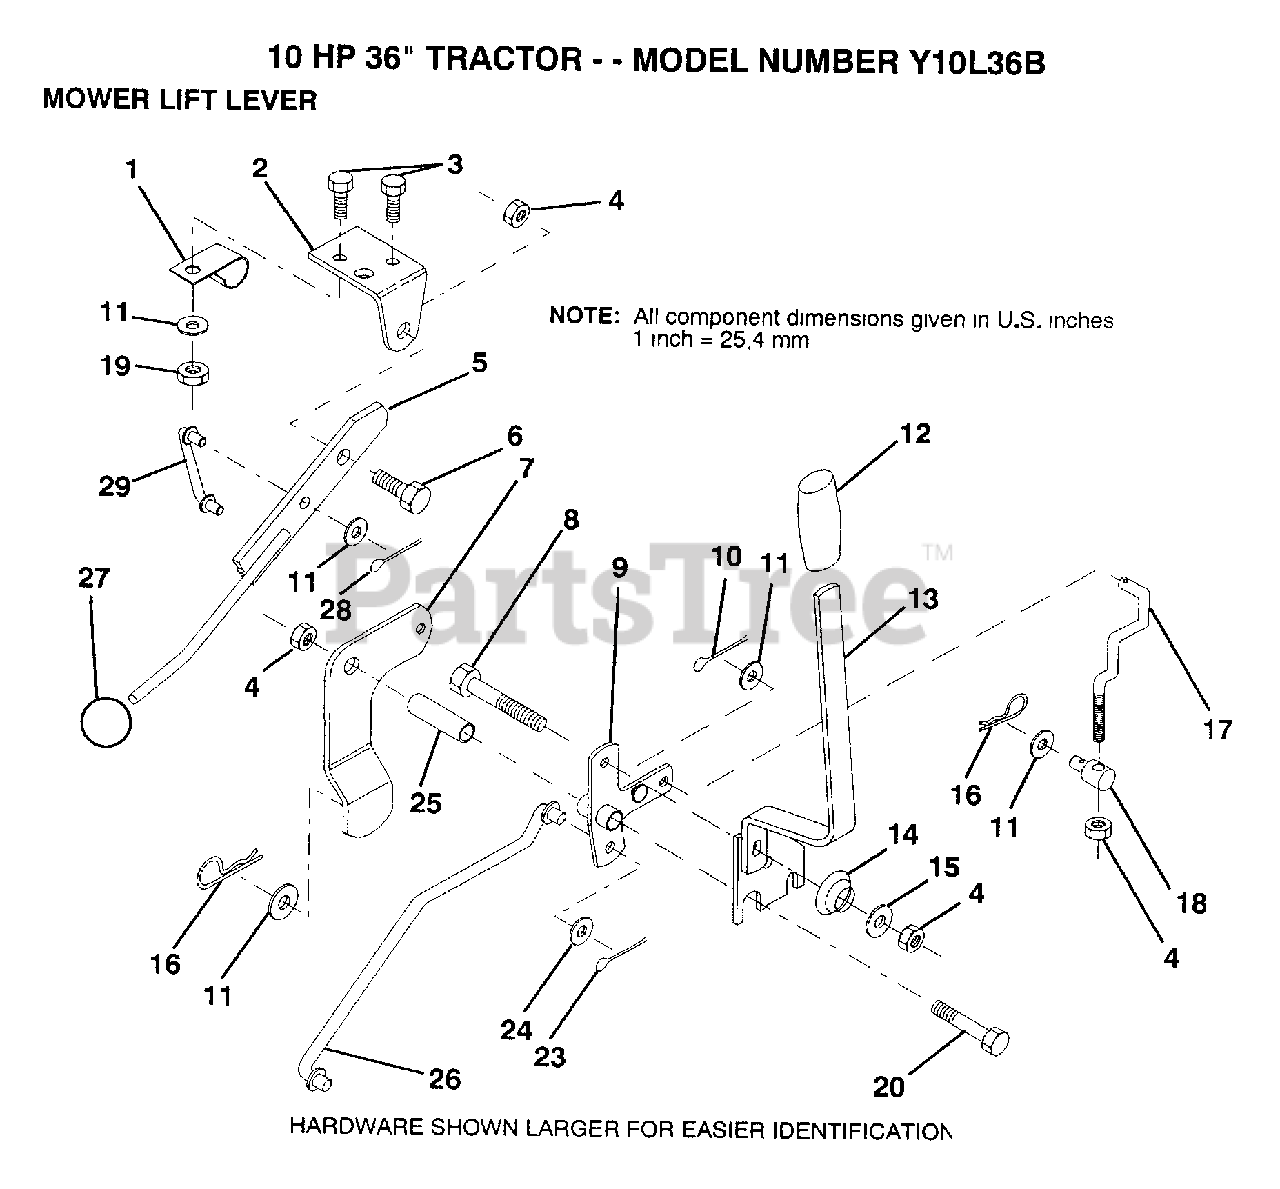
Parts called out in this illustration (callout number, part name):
1	"CLIP,INSULATOR"
2	BRKT CLUTCH
3	BOLT
5	CLUTCH LEVER AS
6	"BOLT, SHOULDER LT"
7	MWR CLUTCH ARM AS
8	BOLT
9	"BELLCRANK,LIFT"
10	COTTER PIN
11	WASHER
13	HANDLE.ASM.LIFT
14	SPRING COMPRESSIO
15	WASHER T
16	SPRING.RETAINER
17	"LINK,LIFT FRT"
18	TRUNION
20	BOLT
23	PIN COTTER 1/8
25	TUBE SPACER
26	"ROD,MOWER LIFT "
27	KNOB T(3/8 HOLE)
29	CLUTCH LINK
